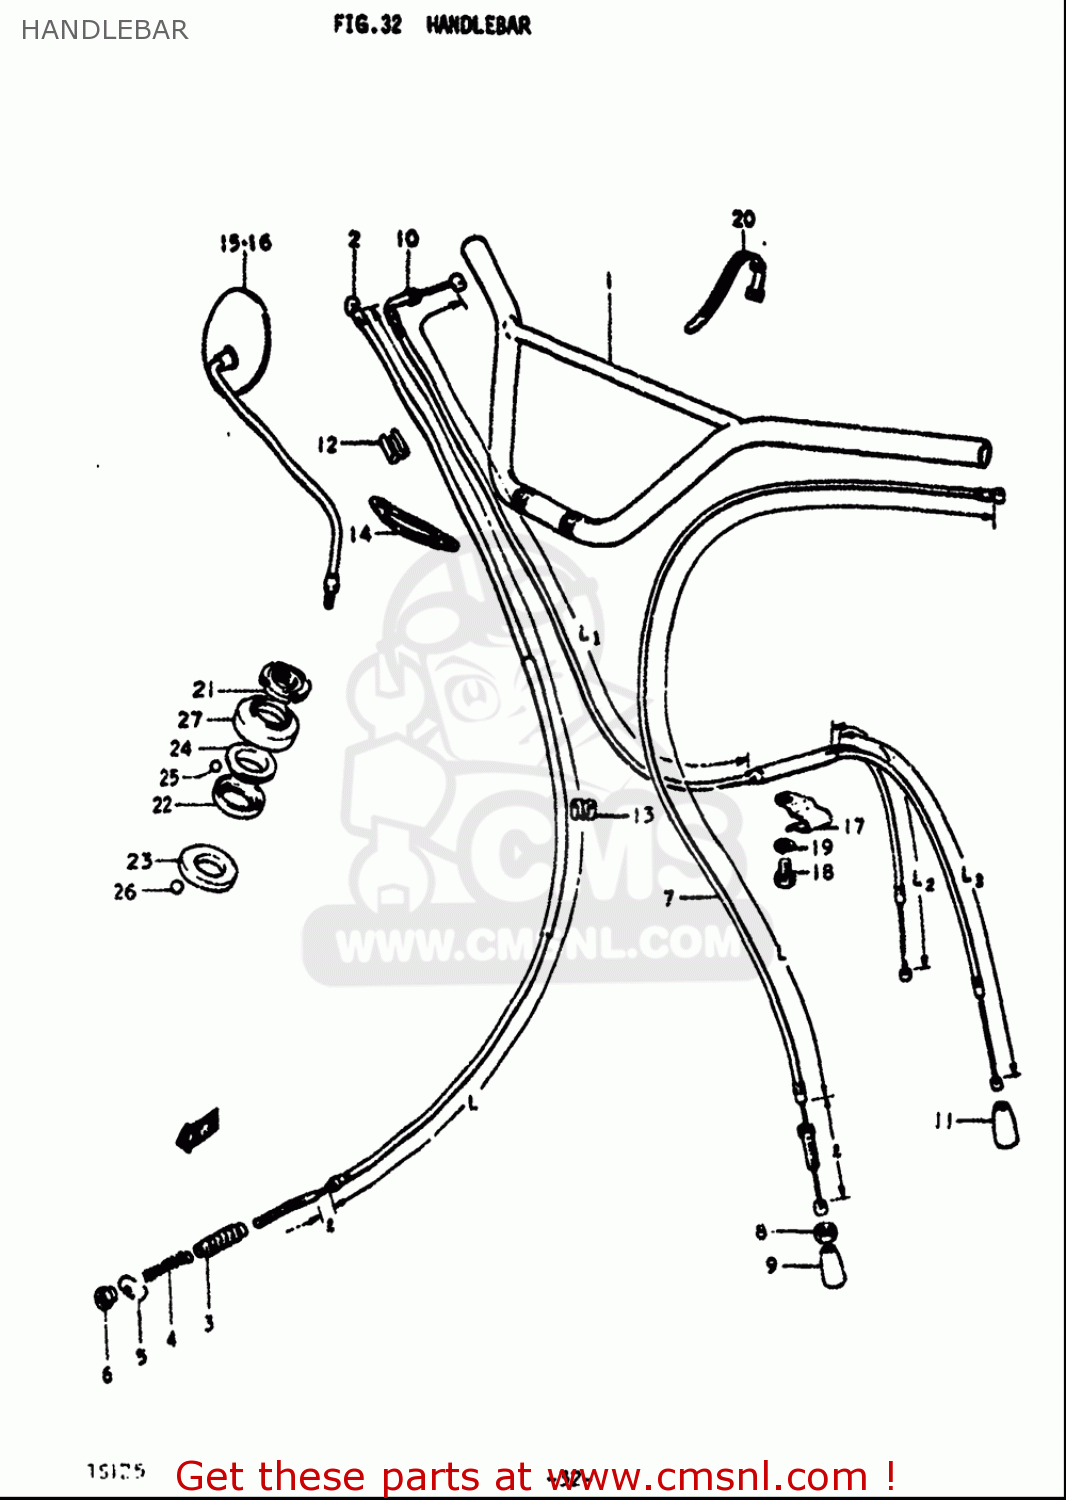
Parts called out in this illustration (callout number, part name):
2	CABLE,FR BRAKE
3	SEAL,DUST(7X16X75)
4	SPRING
5	BRAKE ROD LEVER
6	BRAKE ROD ADJ N
7	CABLE ASSY,CLUTCH
8	NUT
9	SEAL,DUST(7X18X30)
10	CABLE ASSY,THROTTLE
11	SEAL,DUST(7X18X30)
12	CLIP
13	CLIP
15	MIRROR ASSY,RR VIEW,R
16	MIRROR ASSY,RR VIEW,L
18	BOLT
19	WASHER,LOCK
20	CLAMP(L:120)
21	NUT,STEERING STEM(25X44X10)
22	RACE,STEERING INNER UPR
23	LACE,STEERING INNER LWR
24	RACE,STEERING OUTER UPR
25	BALL
26	BALL
27	STEERING DUST S
